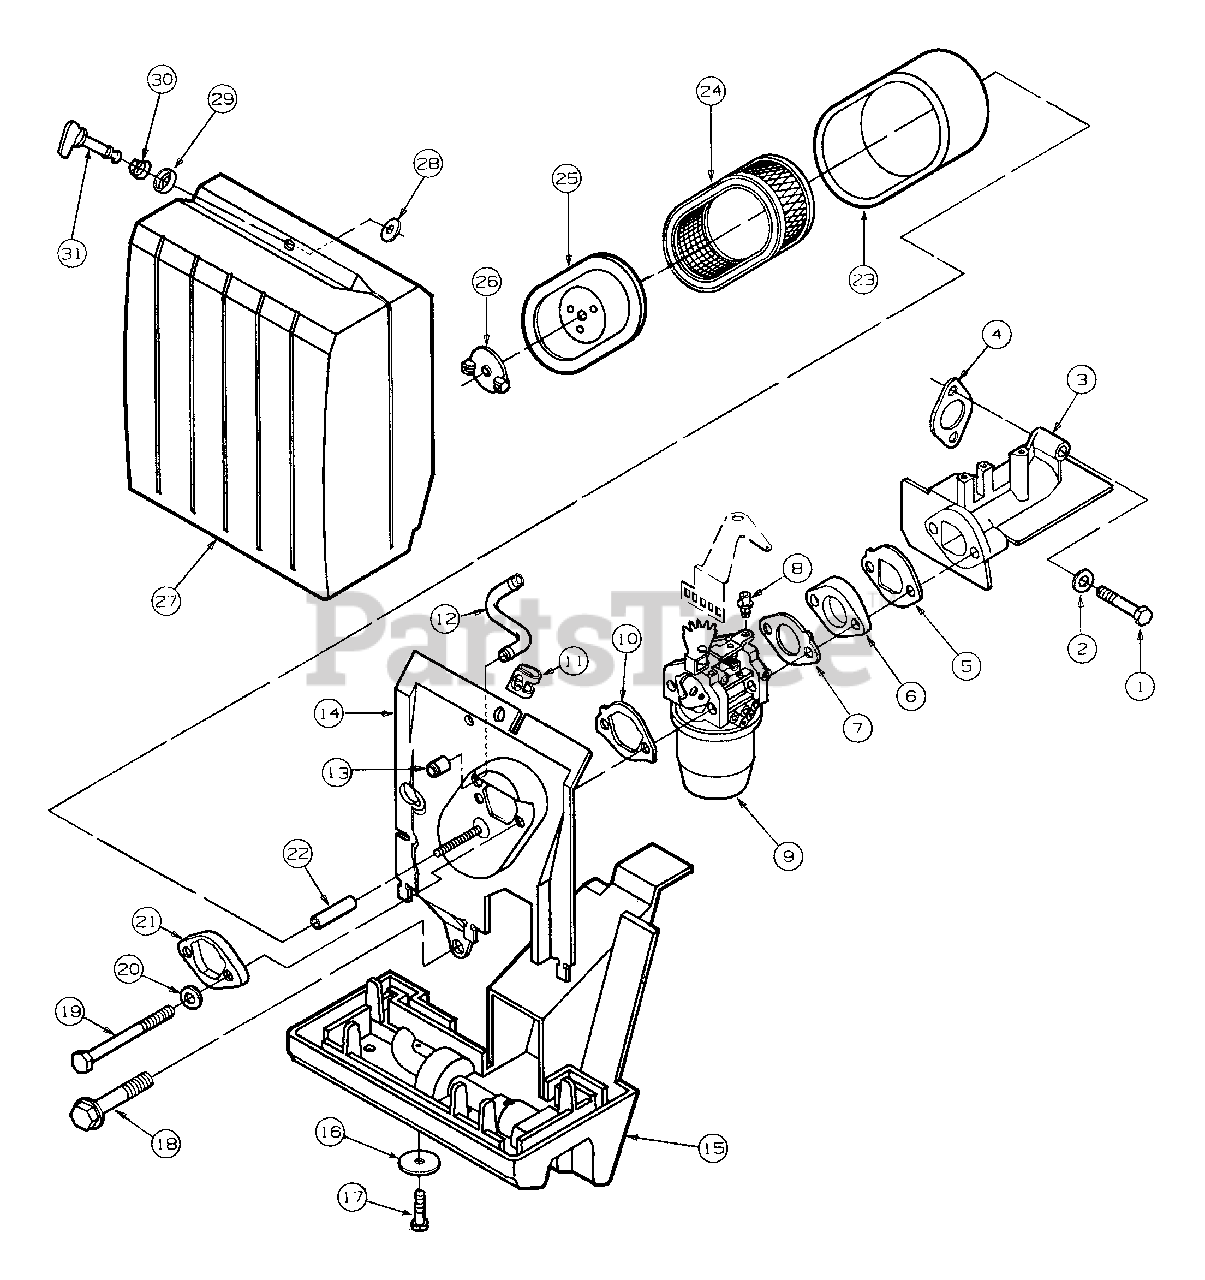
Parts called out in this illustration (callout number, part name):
1	Screw, Hx Hd Cap, M8 x 1.25 x 50
2	Washer, Flat, M8
3	Elbow, Intake
4	Gasket, Intake
5	Gasket, Insulator
6	Insulator, Carburetor
7	Gasket, Insulator
9	Carburetor,
10	Gasket, Air Cleaner
11	Receptacle, Fastener
12	Tube, Breather
14	Pan Assembly, Air Cleaner
15	Duck, Air Inlet
16	Washer, Fender
17	Screw, Pan Hd TT, #10-16 x .5
18	Screw, Hx Hd TT, M8 x 1.25 x 16
19	Screw, Hx Hd TT, M6 x 1 x 90
20	Washer, Flat, M6
21	Support, Carburetor
22	Seal, Air Cleaner Spacer, .625
23	Wrapper, Air Filter
24	Filter, Air
25	Cover, Air Filter
26	Nut, Wing, 1/4-20
27	Cover, Air Cleaner
28	Washer, Nylon
31	Fastener, 1/4 Turn
